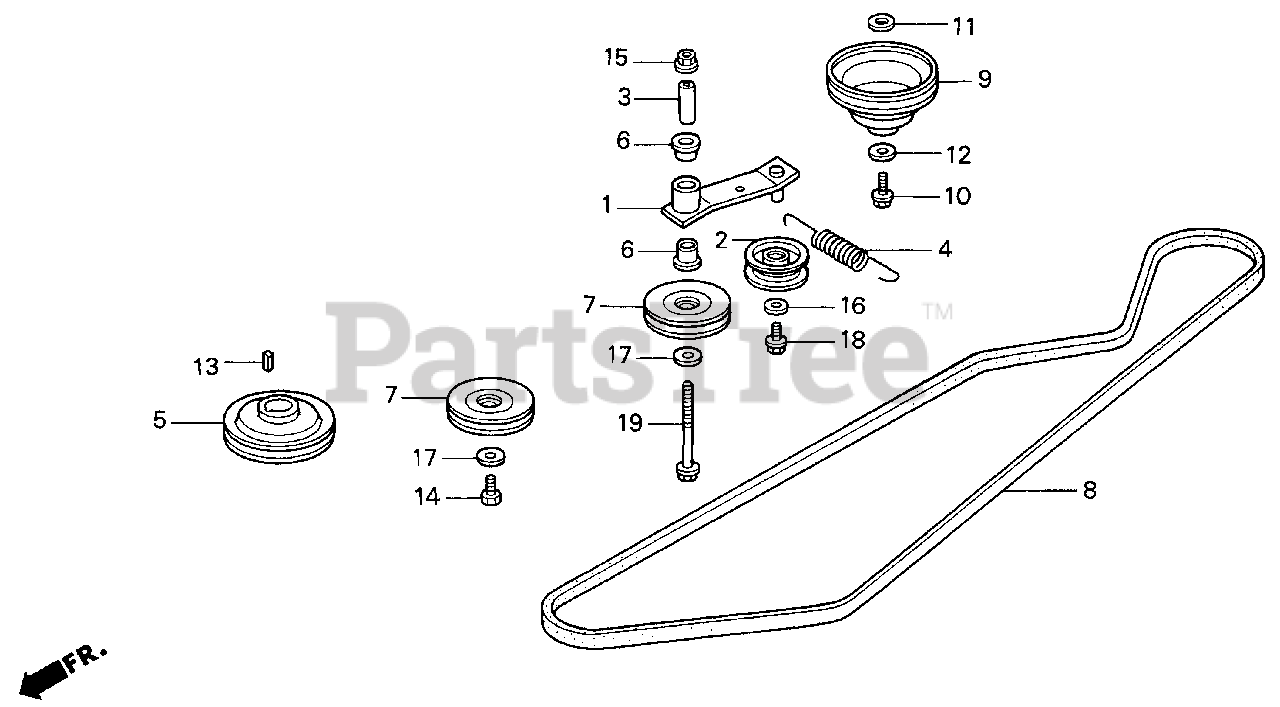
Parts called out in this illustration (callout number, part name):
1	ARM, TENSIONER
2	ROLLER, TENSIONER
3	COLLAR, TENSIONER ARM
4	SPRING, PRIMARY BELT TENSION
5	PULLEY, ENGINE (109.5MM)
6	BUSH, TENSIONER ARM (15X19X14)
7	PULLEY, TENSIONER (80MM)
8	V-BELT (LB-86)
9	PULLEY, TRANSMISSION (109.5MM) (ENGINE)
10	BOLT, FLANGE (8X20)
11	WASHER (17MM)
12	WASHER (8MM)
13	KEY (7X7X18)
14	BOLT, HEX. (8X16)
15	NUT, FLANGE (8MM)
16	WASHER, PLAIN (6MM)
17	WASHER, PLAIN (8MM)
18	BOLT, FLANGE (6X12)
19	BOLT, FLANGE (8X100)
